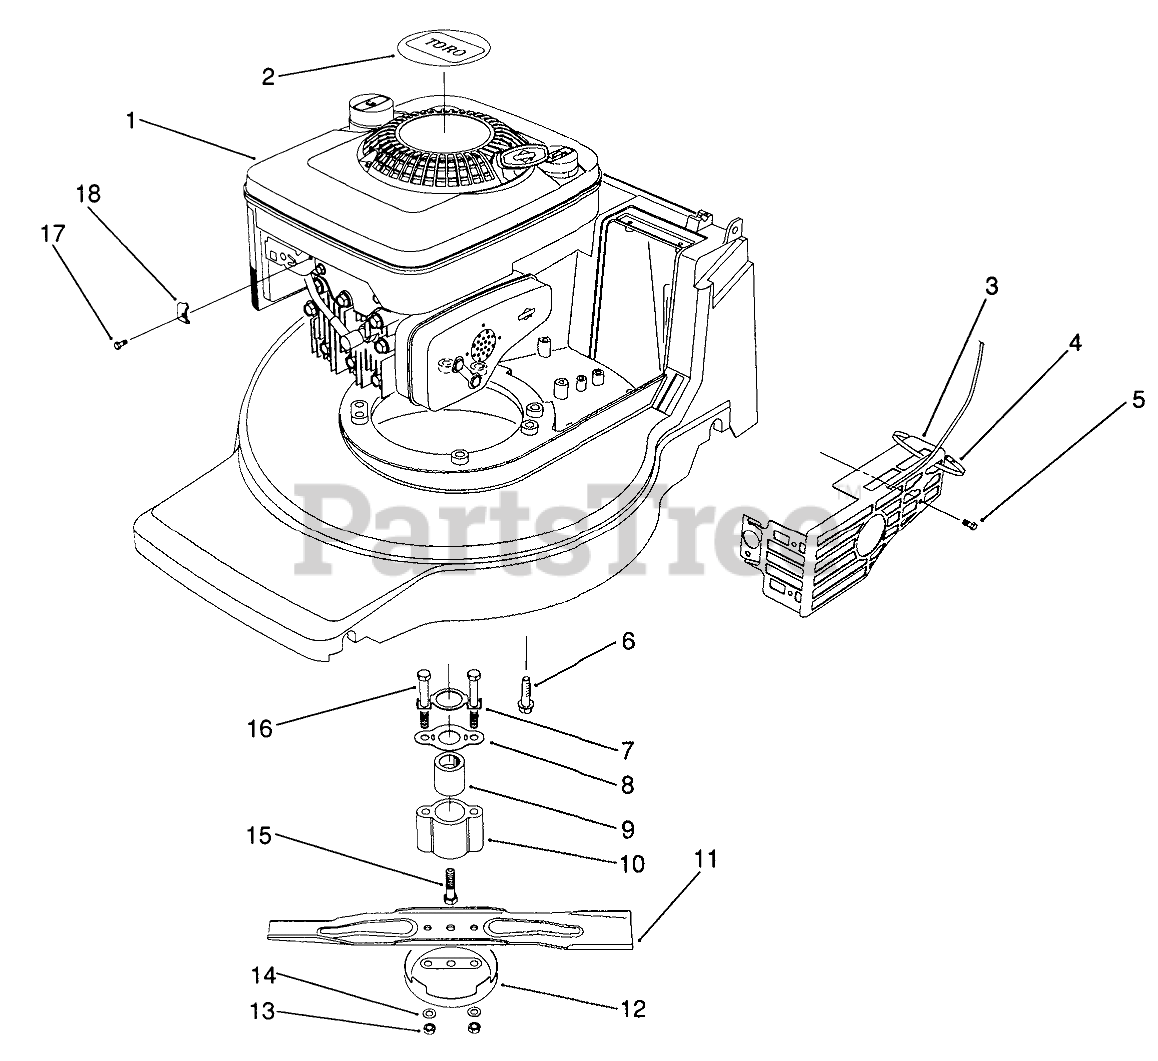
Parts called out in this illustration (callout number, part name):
1	Engine-B & S Quantum
2	DECAL - RECOIL
3	MUFFLER GUARD F/W
4	TIE-CABLE
5	SCREW W/ENGINE
6	3/8-16 X 2 CAPSCREW
7	BLADE RETAINER BRKT
8	SPRING FRICTION
10	RETAINER
11	Blade-48cm
12	Anti Scalp Cup
13	Nut
14	WASHER
15	SCREW - CRANKSHAFT
16	SCREW - BLADE
17	Screw
18	CLAMP-CASING
